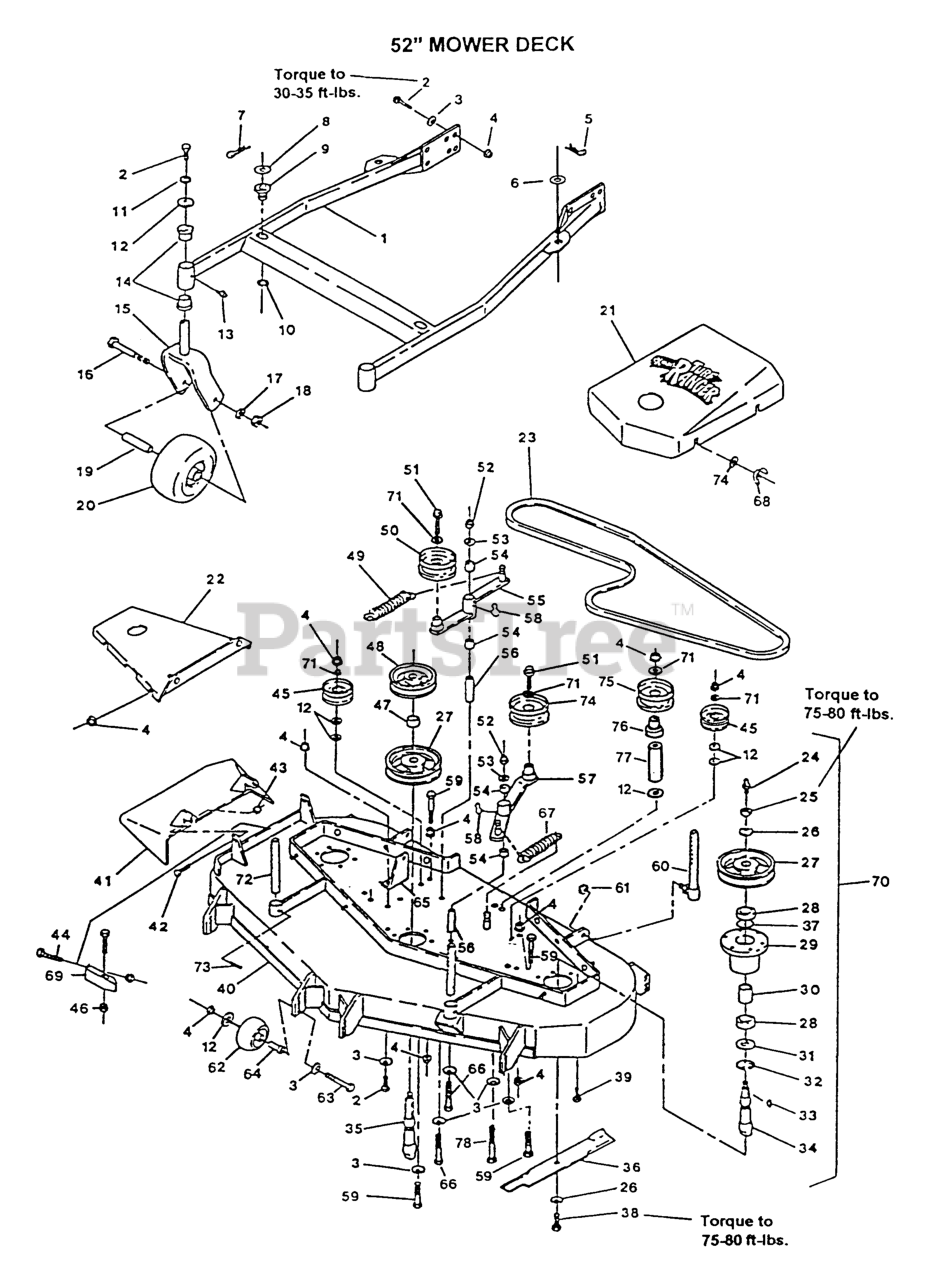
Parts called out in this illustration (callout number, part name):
5	PIN,HAIR COTTER
8	WASHER-FLAT
9	BUSHING-DECK
12	WASHER
14	BEARING-FLANGED
23	BELT,BLADE DRIVE
26	WASHER-SPRING
27	SHEAVE,BLADE DRIVE
28	BEARING,HD SPINDLE
29	HOUSING,BEARING
30	SPACER,BEARING
31	SEAL,MECHANICAL DUST
32	RING,SNAP WLDS N5000-244
34	SPINDLE - BLADE
35	SPINDLE -CENTERBLADE
39	SCRW,TPTTE HH
41	WLD,CHUTE DISCHARGE
45	IDLER,PULLEY
47	SPACER-TUBE
48	SHEAVE,MOWER DRIVE
49	SPRING-EXTENSION
50	IDLER,PULLEY
54	SLEEVE-BEARING
55	ASM,IDLER ARM
56	BUSHING-PIVOT, IDLER
57	ASM,IDLER ARM
62	ROLLER-SCALP, ANTI
64	BUSHING-ROLLER
65	BRACKET,SPRING ANCHOR
66	SCREW-HH
67	SPRING-EXTENSION
68	NUT-WING
69	WLD,BAFFLE DISCHARGE
72	ROD,DECK SUPPORT
74	PULLEY-IDLER
75	PULLEY-IDLER
76	BUSHING,IDLER
77	SPACER-FENDER
